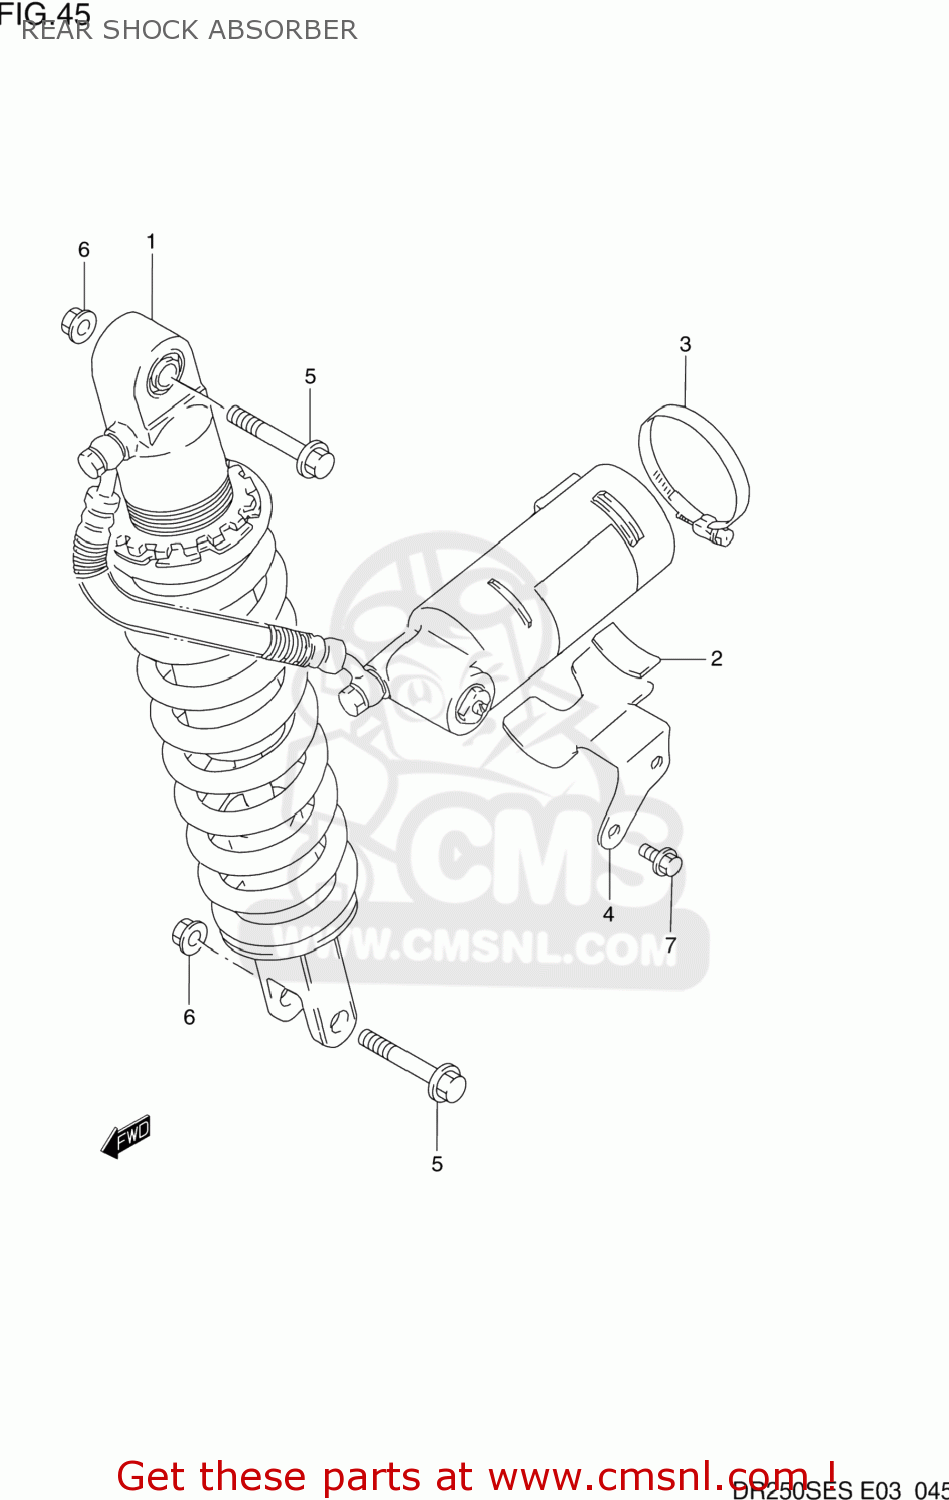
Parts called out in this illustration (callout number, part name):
1	ABSORBER ASSEMBLY,REAR SHOCK
2	CUSHION,REAR SHOCK ABSORBER
3	CLAMP
4	BRACKET,RESERVOIR TANK
5	BOLT,REAR SHOCK ABSORBER
6	NUT
7	BOLT
